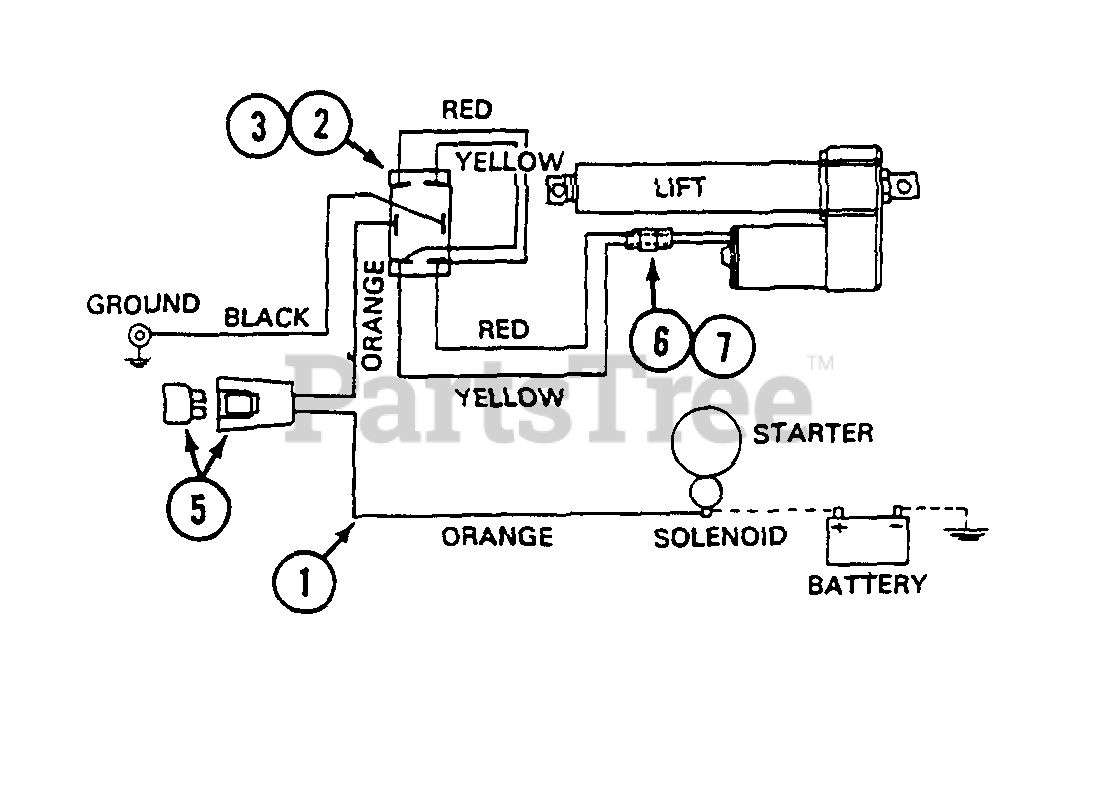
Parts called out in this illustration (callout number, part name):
1	HARNESS - wire
3	NUT - 15/32 - 32 with boot (switch mounting)
5	KIT - fuse holder
5	FUSE - 30 amp
6	CONNECTOR - wire harness
7	CONNECTOR - lift actuator
